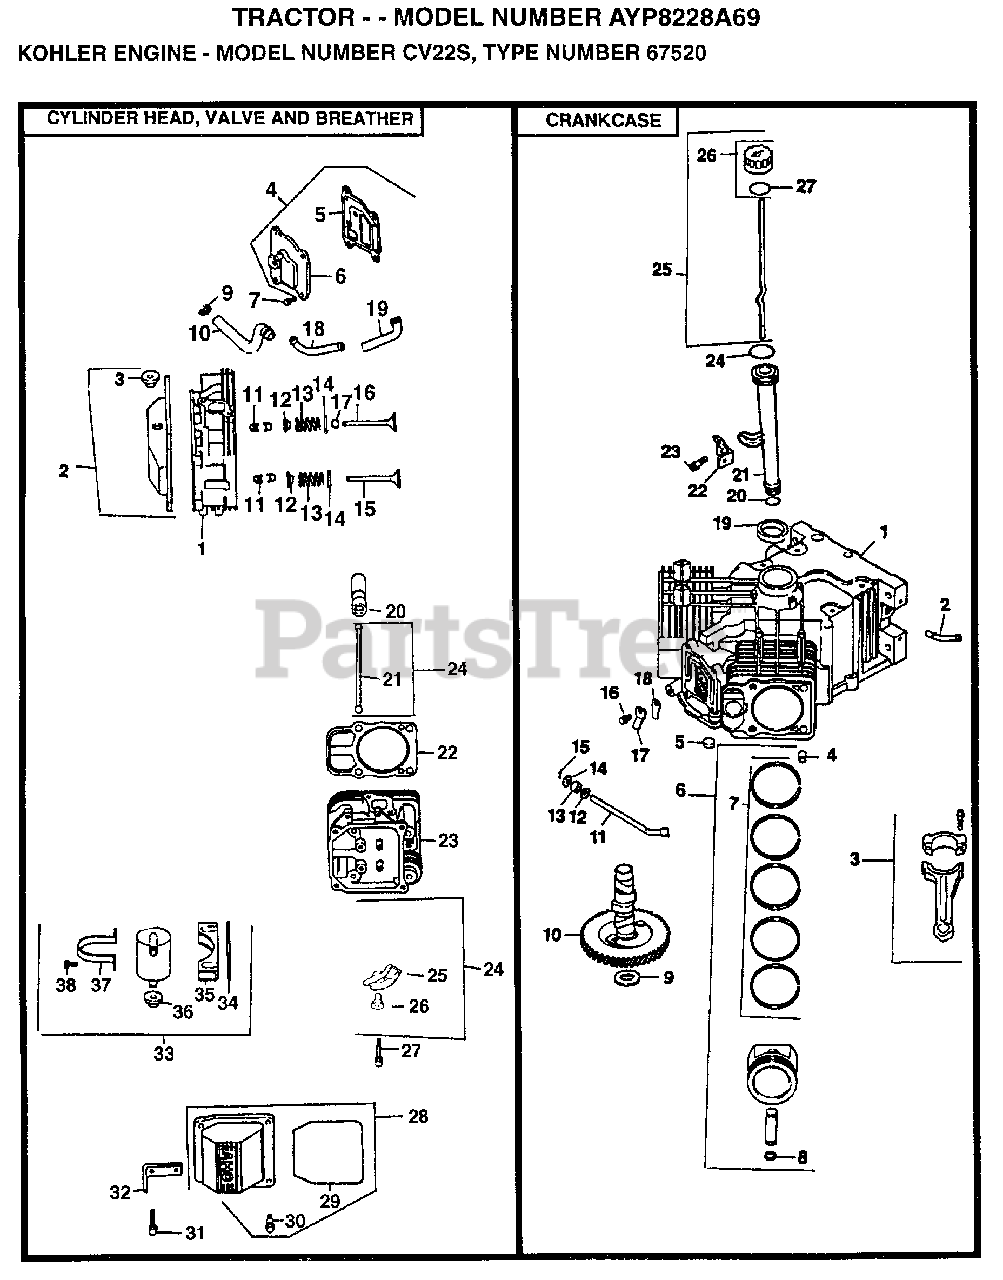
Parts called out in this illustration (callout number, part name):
1	HEAD ASSEMBLY
1	CYLINDER BLOCK
2	KIT, VALVE COVER, BREATHER
3	GROMMET, RUBBER
3	CONNECTING ROD
4	KIT, BREATHER COVER WITH GASKET
4	PIN, DOWEL LOCATING
5	GASKET, BREATHER
6	COVER, BREATHER
6	PISTON WITH RING SET
7	SCREW HEX FLANGE
8	RETAINER, PISTON PIN
9	SHIM, CAMSHAFT, YELLOW
10	HOSE, BREATHER
11	KIT, RETAINER
11	SHAFT, GOVERNOR CROSS
12	CAP, VALVE SPRING
12	WASHER, PLAIN
13	SPRING, VALVE
13	SEAL ,GOVERNOR CROSS SHAFT
14	RETAINER, SPRING
15	VALVE, EXHAUST, STANDARD SIZE
16	VALVE, INTAKE, STANDARD SIZE
16	SCREW, MOUNTING
17	SEAL, VALVE STEM
17	RETAINER, REED
18	REED, BREATHER
19	HOSE,BREATHER
19	SEAL, OIL, FRONT
20	LIFTER, VALVE
20	O-RING, LOWER OIL FILL TUBE
21	TUBE, OIL FILL
22	GASKET, CYLINDER HEAD
22	BRACKET, OIL FILL TUBE
23	HEAD ASSEMBLY
24	KIT, VALVE TRAIN
24	O-RING, UPPER OIL FILL TUBE
25	DOPSTICK ASSEMBLY
26	PIVOT, ROCKER ARM
26	KIT, OIL FILL CAP
27	SCREW, ROCKER ARM
27	O-RING, DIPSTICK
28	KIT, VALVE COVER, PLAIN
32	STRAP, LIFTING
33	KIT, BREATHER SEPARATOR
35	BRACKET, BREATHER SEPARATOR
36	GROMMET, RUBBER
37	STRAP, BREATHER SEPARATOR
